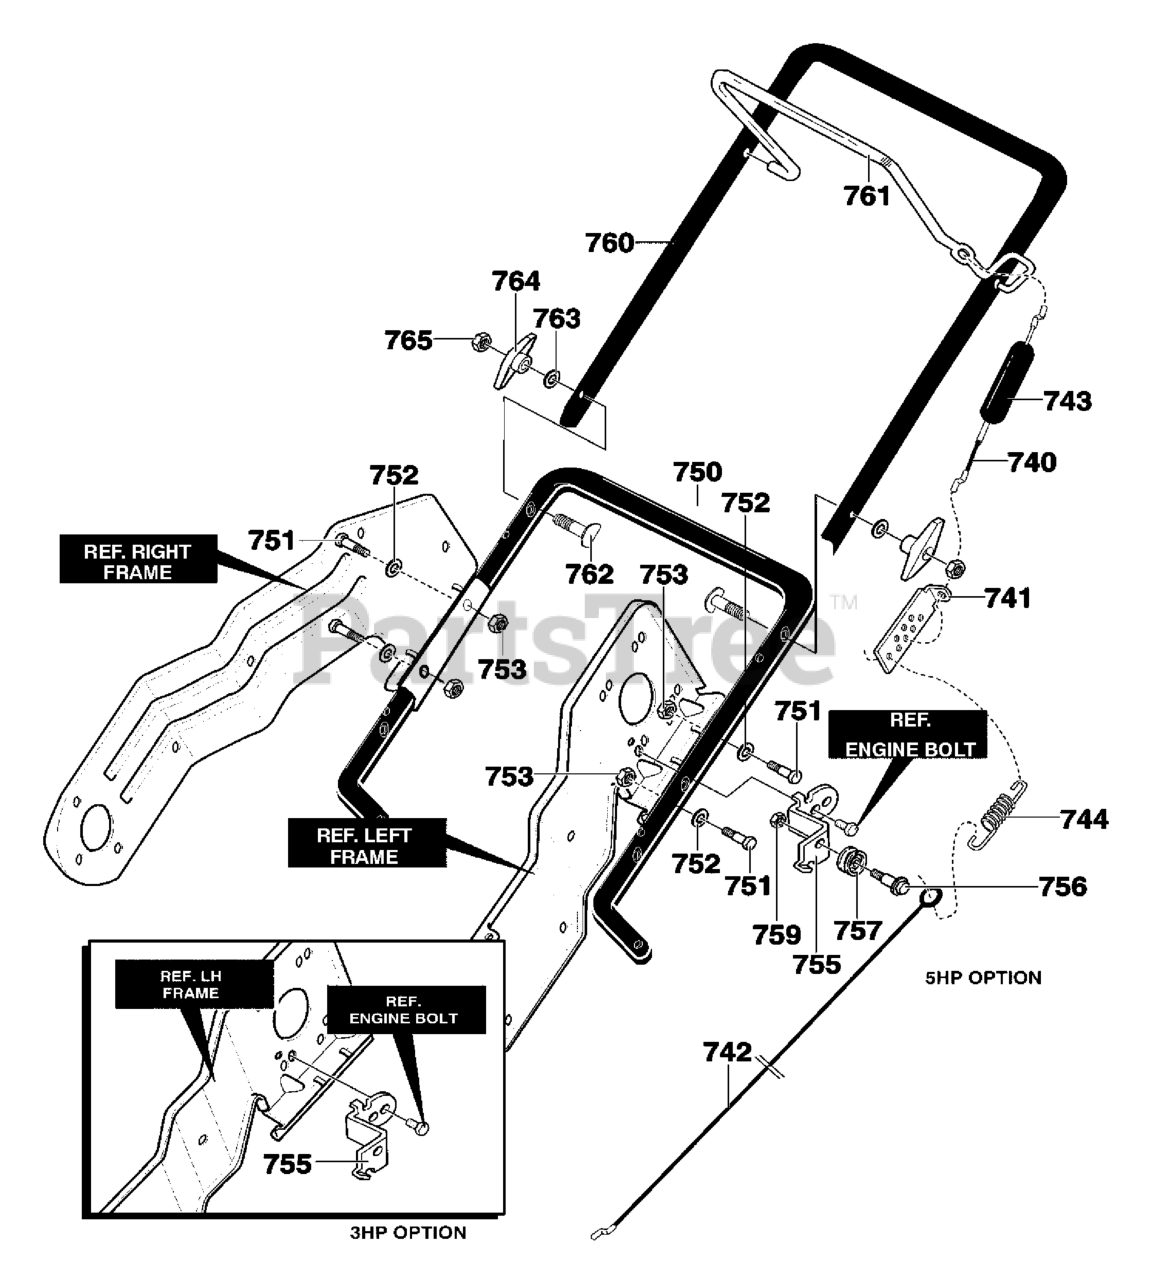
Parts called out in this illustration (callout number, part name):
740	CABLE, UPPER
741	BRKT, CABLE ADJ
742	CABLE LOWER CONTROL
743	BOOT, CLUTCH SPRING
750	HANDLE LOWER
751	SCREW, 1/4-20X1.25
752	WASHER, FLAT .281X.63X.065
753	NUT, 1/4-20 REGHEXCTRLK
755	BRACKET, CABLE
756	BOLT, .375X.375 1/4-20
757	PULLEY, .906X.305
759	NUT, 1/4-20 REGHEXCTRLK
760	HANDLE, UPPER
761	BAIL, CONTROL
762	BOLT, 5/16-18X2.00
763	WASHER, FORM
764	KNOB,T
765	NUT, 5/16-18 REGHEX
